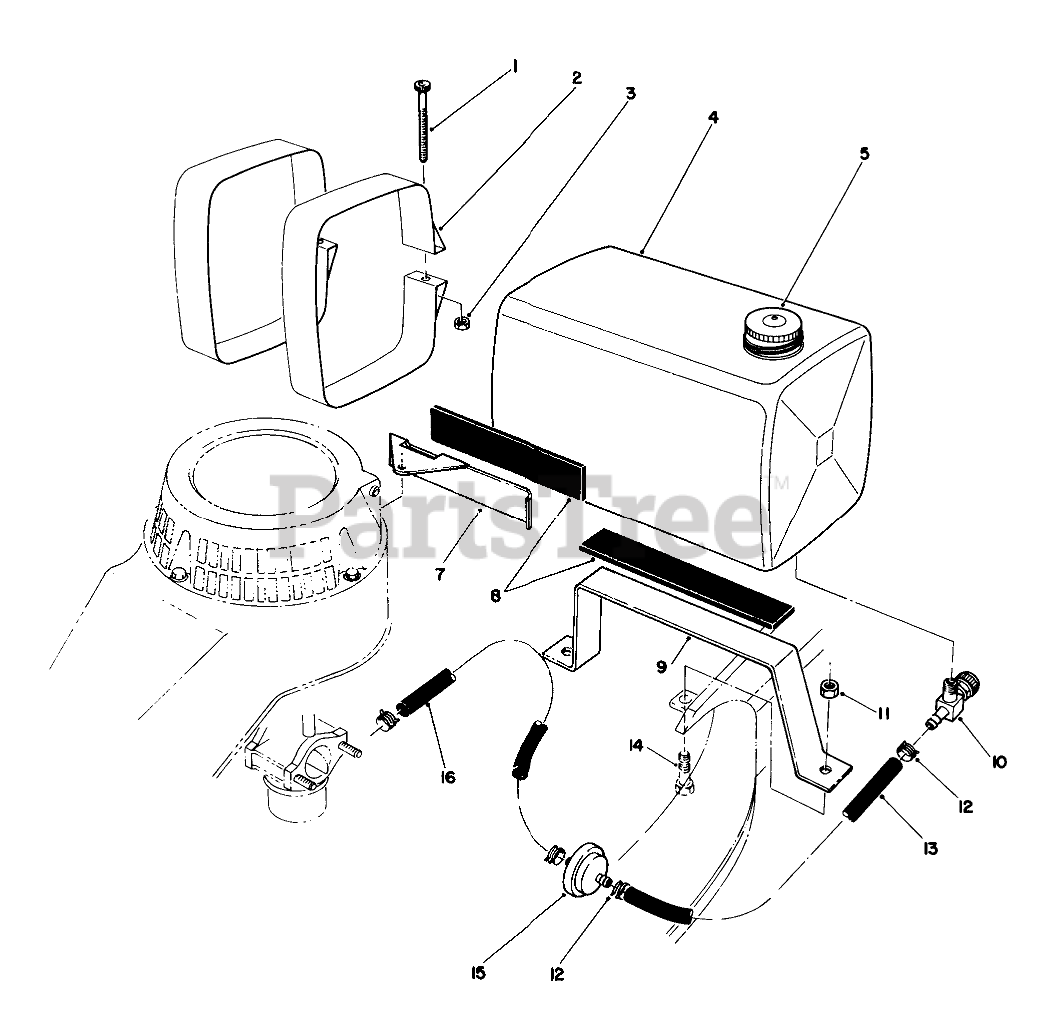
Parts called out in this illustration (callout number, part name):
1	SCREW-HSH
2	TANK MTG STRAP WA
3	NUT-HEX
4	Tank-Gas (Incl. Ref. #5)
5	CAP CAP
7	FRT TANK MOUNT
8	ISOLATOR PAD
9	BOTTOM TANK MOUNT
10	.125 ID SHUTOFF VALVE
11	NUT-LOCK, NI
12	CLAMP-FUEL LINE
13	LINE-GAS
14	SCREW-HH
15	FILTER-FUEL
16	HOSE-FUEL
